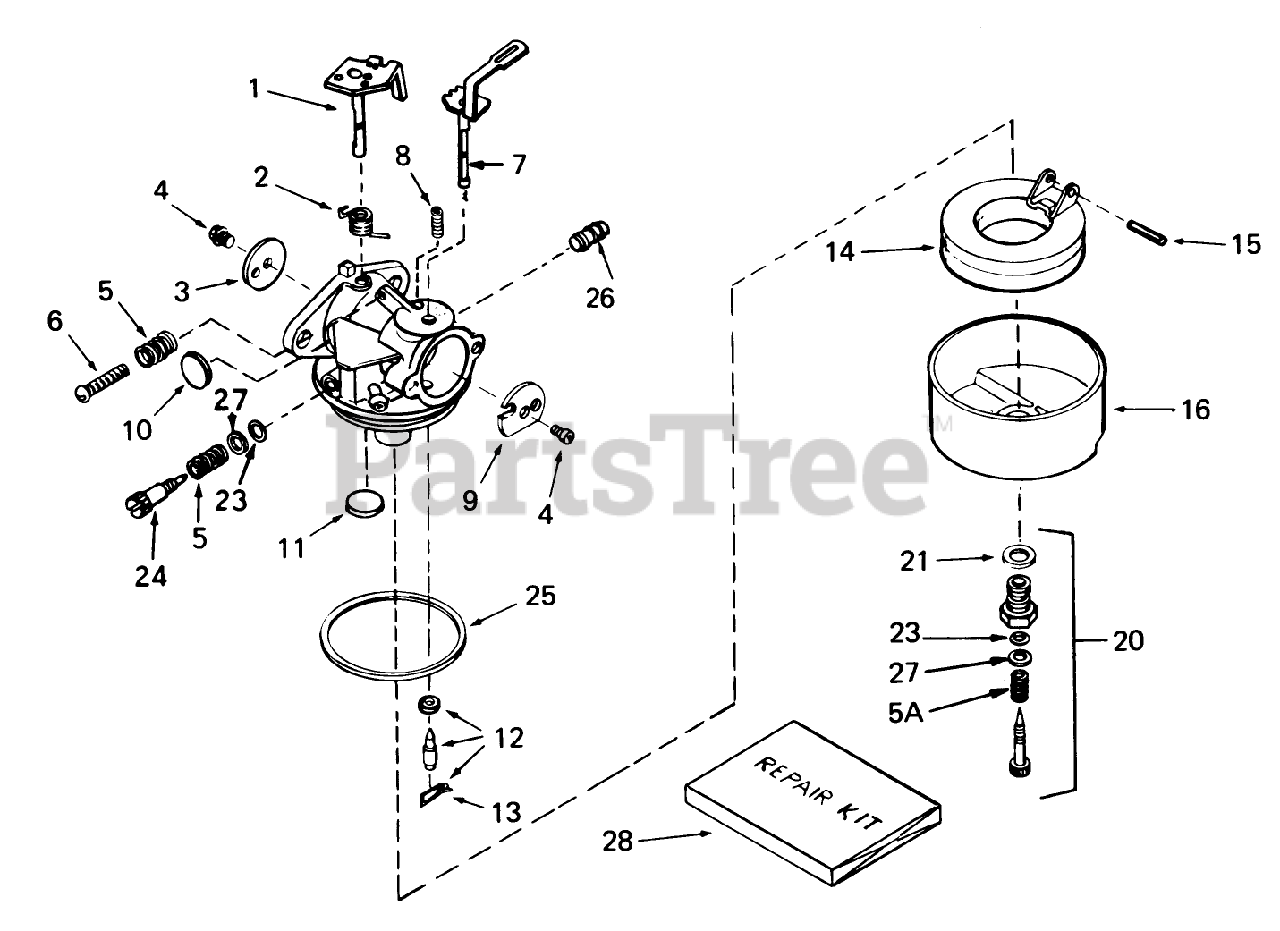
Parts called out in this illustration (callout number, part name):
1	Shaft/Lever-Throttle
2	Spring, Throttle Return
3	Shutter-Throttle
4	Screw-Shutter
5	Spring-Tension
5A	Spring
6	Screw-Throttle Crack Screw / Idle Speed
7	Shaft Lever Assy., Choke
8	Spring-Positioning, Choke
9	Choke Shutter
10	Plug-Welch, Idle Mixture Well
11	Plug-Welch, Atmospheric Vent
12	Inlet Needle, Seat Clip Assy. (Incl. No. 13)
13	Clip-Spring
14	Float
15	Shaft-Float
16	Bowl-Float (no drain)
20	Adjustment Screw Assembly, Main (Incl. Nos. 5A, 21, 23 27)
21	Washer-Bowl Nut
23	ORing
24	Screw Main Adjustment
25	O Ring-Bowl, Float
26	Fuel Fitting
27	Washer
28	Repair Kit
